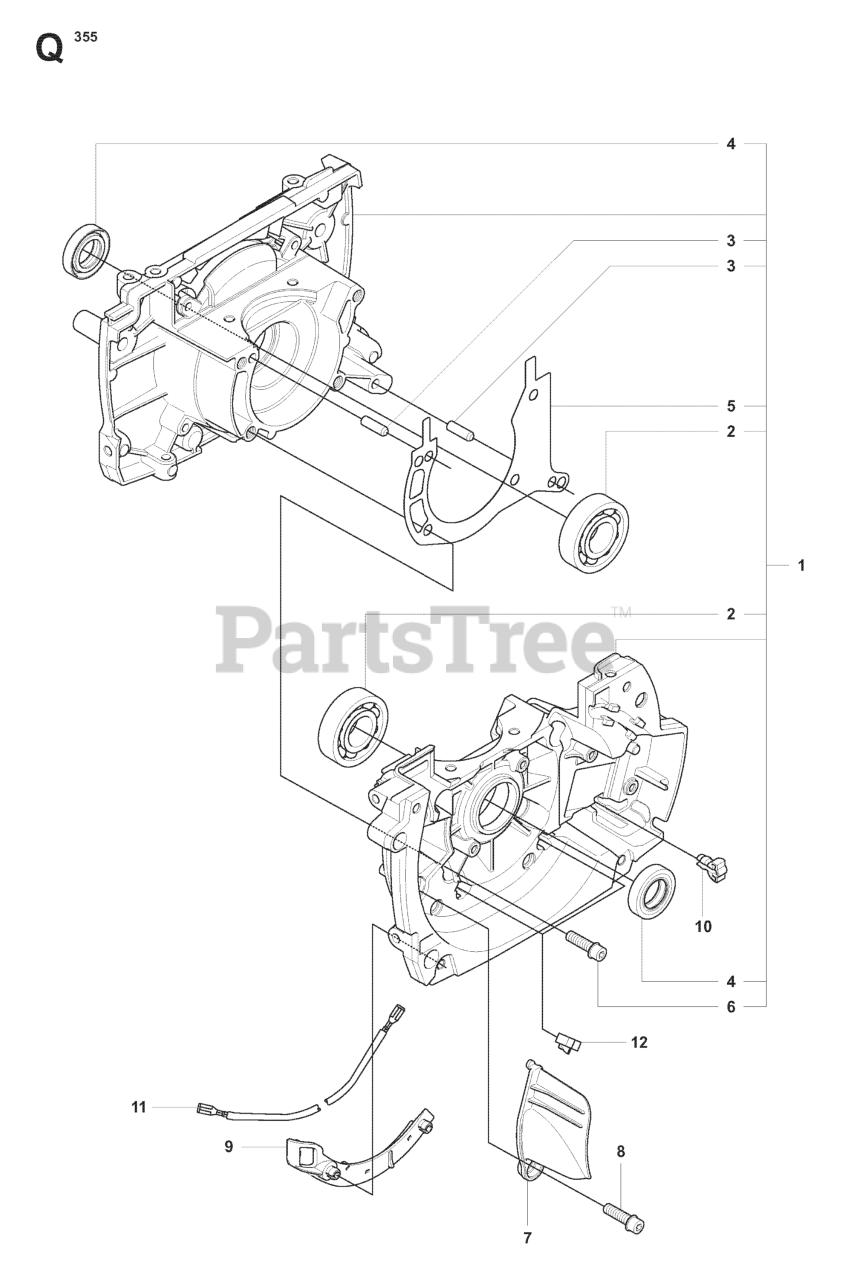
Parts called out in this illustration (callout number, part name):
2	BALL BEARING-6202-C3 SKF
3	PIN 5X14
4	SEALING RING
5	CRANKCASE GASKET
6	SCREW MC6S 5X25
9	CABLE HOLDER
11	SHORT CIRCUIT CABLE
12	GROMMET
